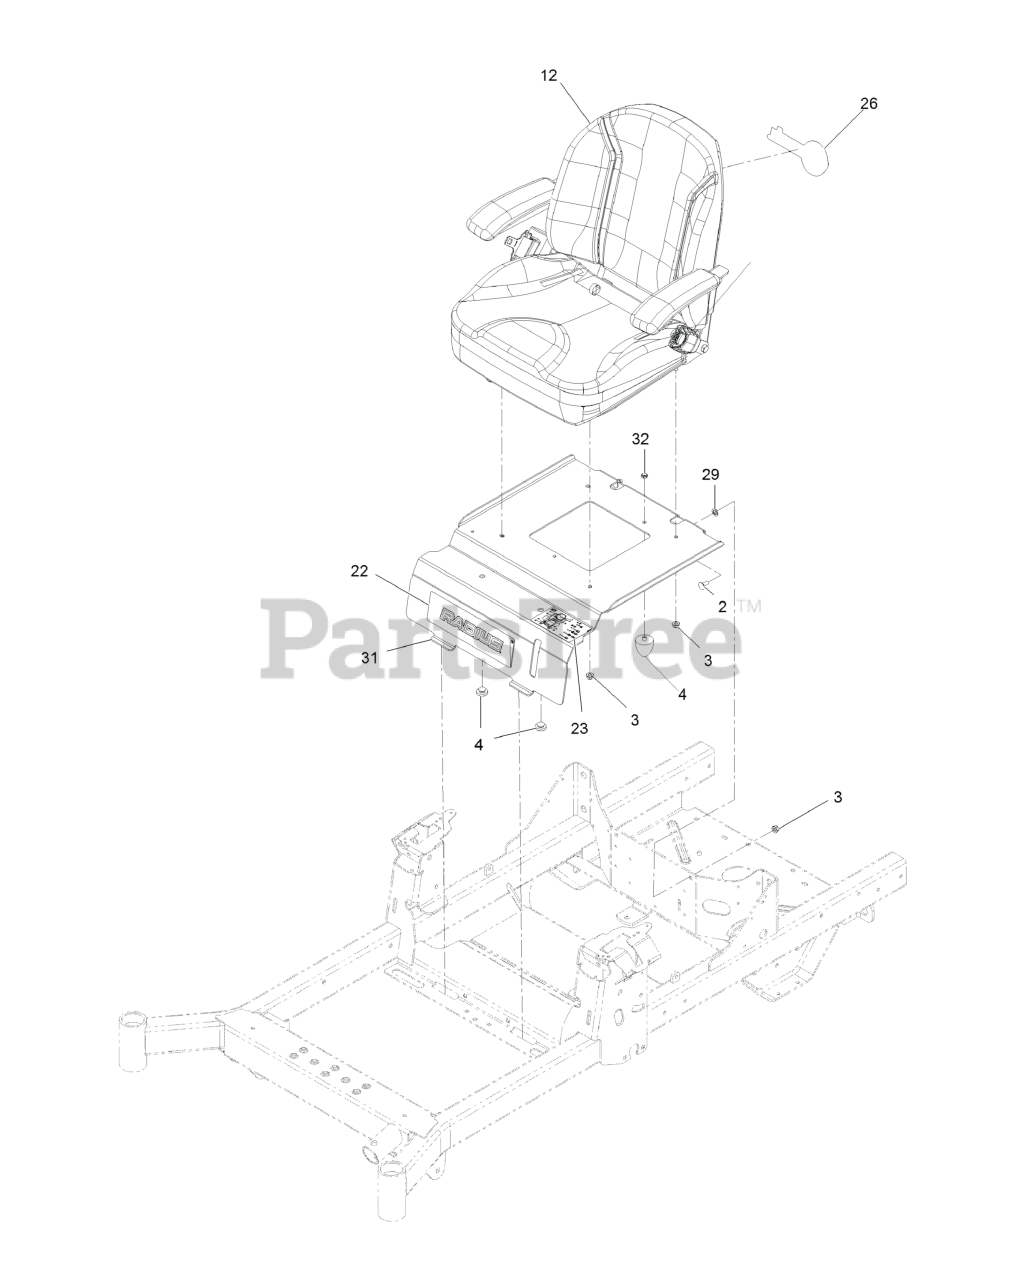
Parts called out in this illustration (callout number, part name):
2	SCREW-CARR
3	NUT-HF, NI
4	BUMPER-SEAT
4	BUMPER-RUBBER
12	ASM-SEAT EXMARK
22	DECAL-RADIUS LOGO
23	DECAL-AID, SERVICE
26	DECAL, EXMARK LOGO
29	Washer-Retaining
31	PLATE-FIXED SEAT
32	NUT-LOCK, NI
